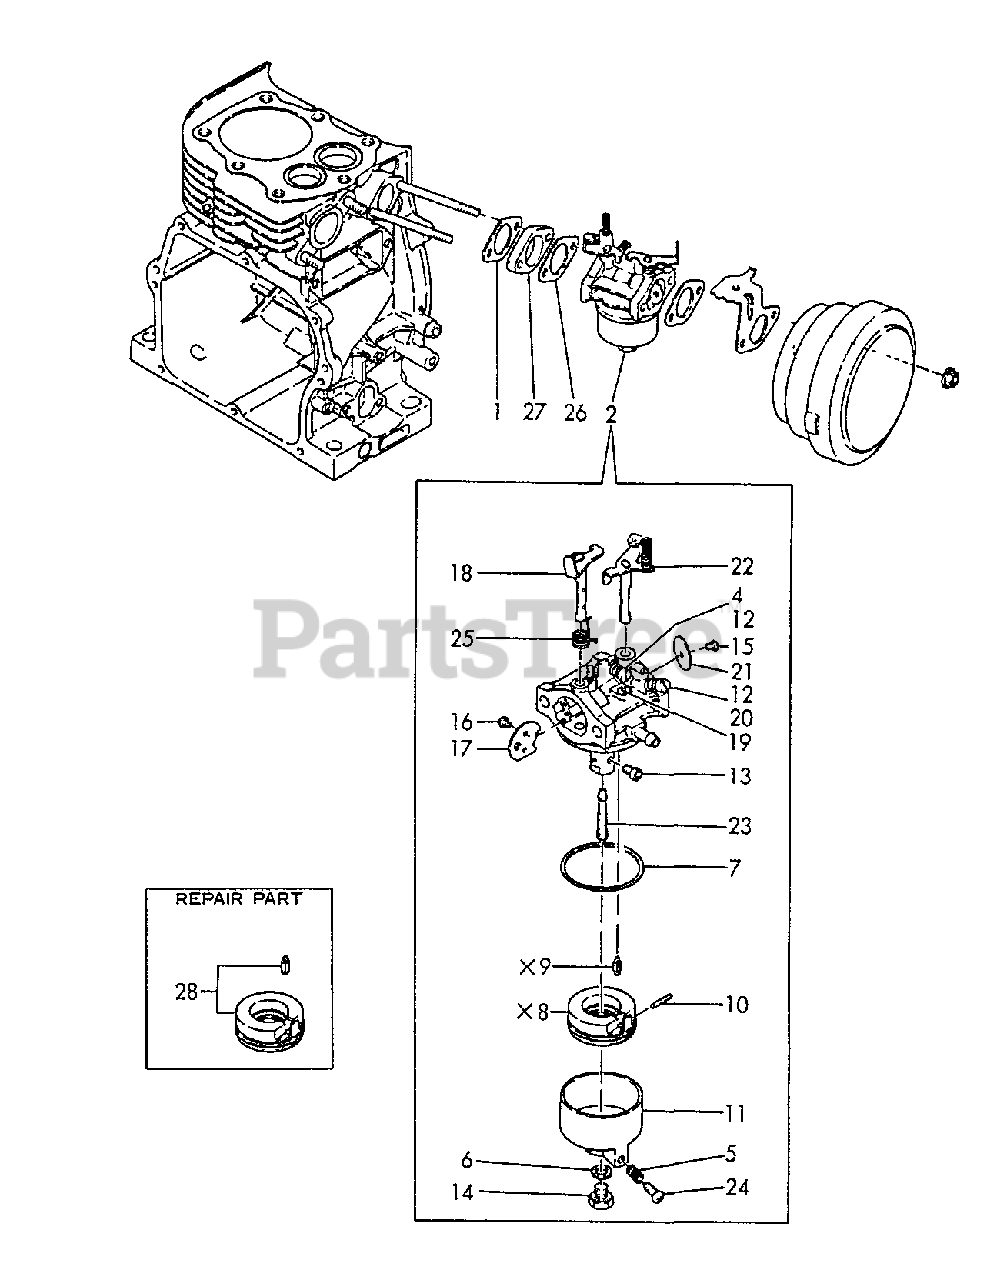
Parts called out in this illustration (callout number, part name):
1	GASKET, EXHAUST
2	CARBURETOR
4	SCREW, THROTTLE
6	WASHER
7	GASKET
8	FLOAT
9	NEEDLE
10	PIN
11	BODY, FLOAT CHAMBER
13	JET, MAIN
14	BOLT
15	SCREW
17	VALVE, CHOKE
18	SHAFT, CHOKE
19	JET, PILOT
20	SCREW, PILOT
21	VALVE, THROTTLE
22	SHAFT, THROTTLE
23	NOZZLE, MAIN
24	SCREW
25	SPRING
26	GASKET, INTAKE
27	INSULATOR, INTAKE
28	NEEDLE ASSY - RUBBER
